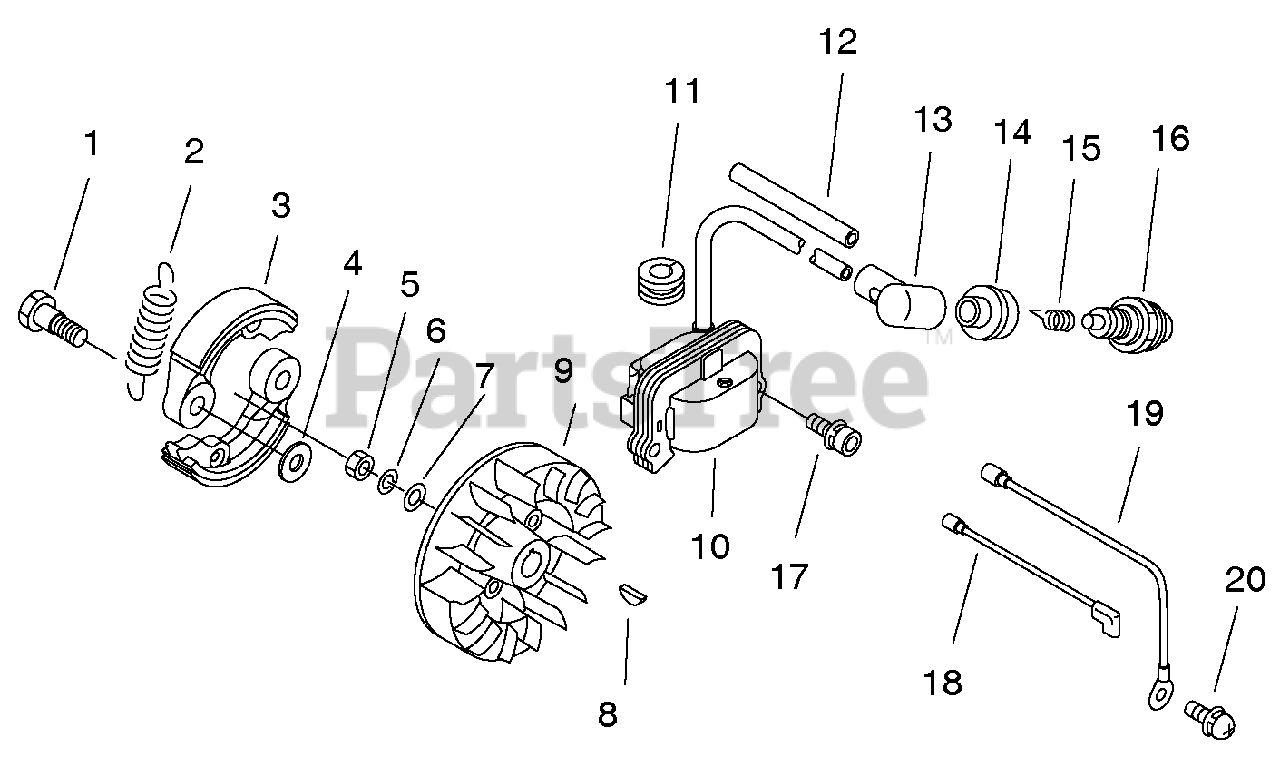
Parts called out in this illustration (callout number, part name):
1	BOLT, CLUTCH M6
2	SPRING, CLUTCH
3	SHOE, CLUTCH
4	WASHER 6.2×19×1.0
5	NUT 8×1.25
6	WASHER, SPRING 8
7	WASHER 8.5×16×1.2
8	KEY, WOODRUFF
9	FLYWHEEL
10	COIL, IGNITION
12	TUBE, PROTECTIVE 6×7×110
13	CAP, SPARK PLUG
14	SEAL, SPARK PLUG
15	TERMINAL, SPARK PLUG
16	SPARK PLUG - BPMR7A
17	BOLT 5×20
18	LEAD 170 MM
19	LEAD - GROUND
20	SCREW 5×10
